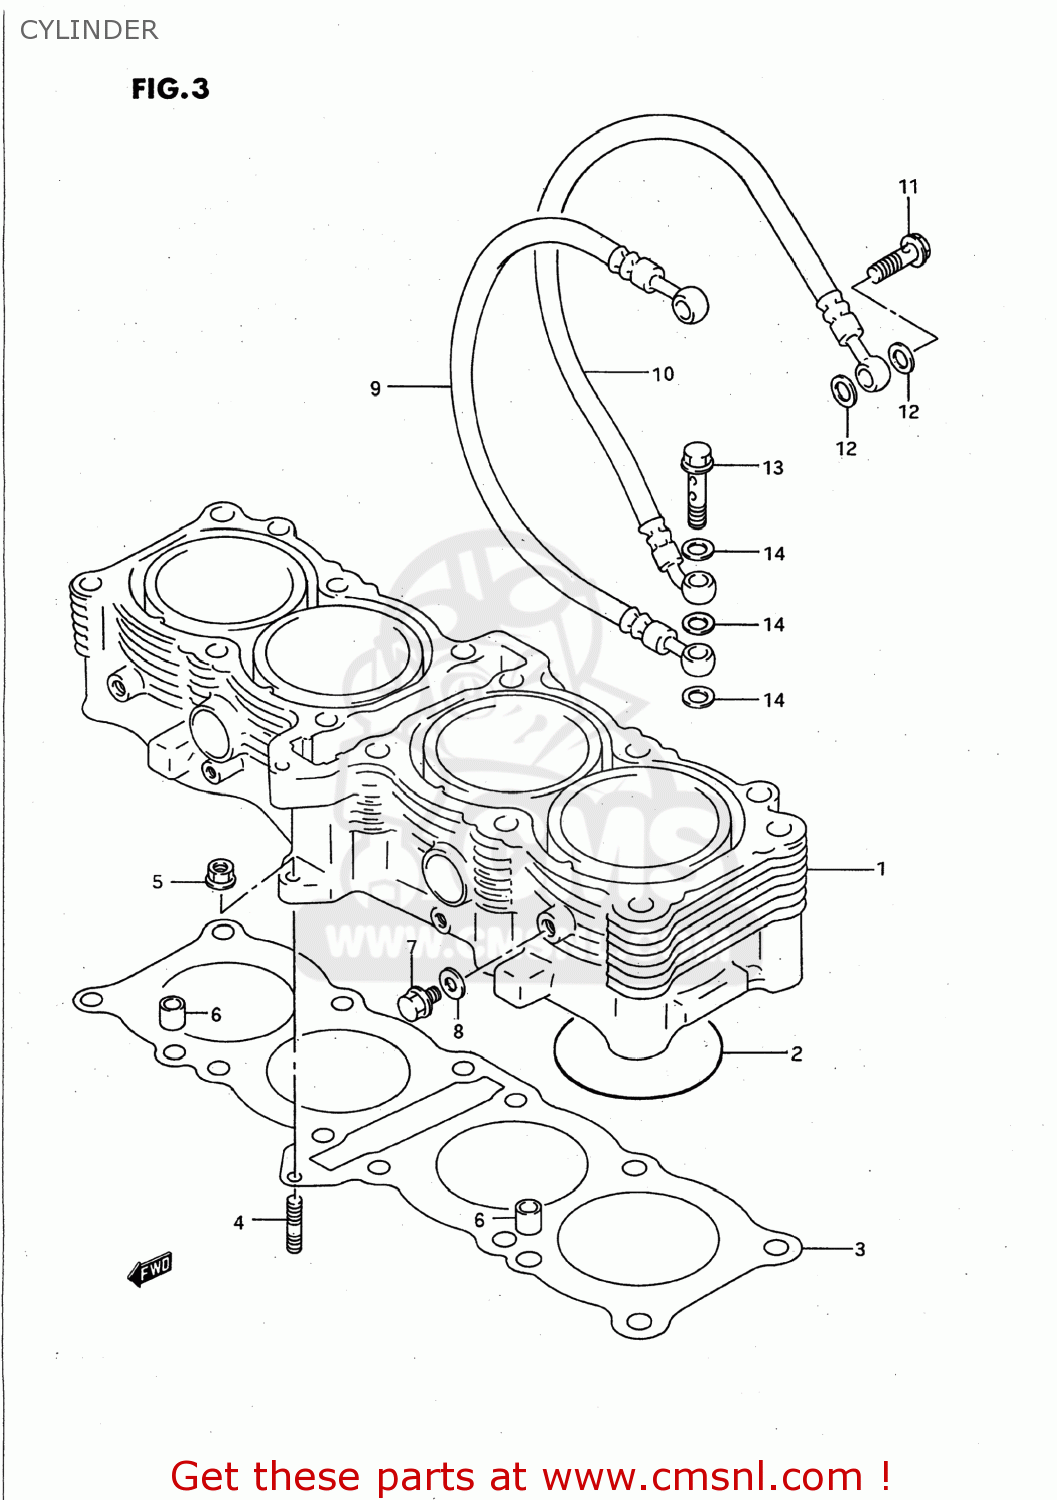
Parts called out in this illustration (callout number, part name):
1	CYLINDER COMP
2	O-RING
3	GASKET,CYLINDER
4	STUD,M6X1X32
5	NUT
6	PIN
7	BOLT,DRAIN
8	GASKET 8.2X14X1 (NAS)
9	HOSE,OIL
10	HOSE,OIL
11	BOLT,OIL PIPE UNION,NO
12	GASKET(8.2X14X1) (NAS)
13	BOLT,OIL PIPE UNION,NO
14	WASHER(10X15X1.5)
